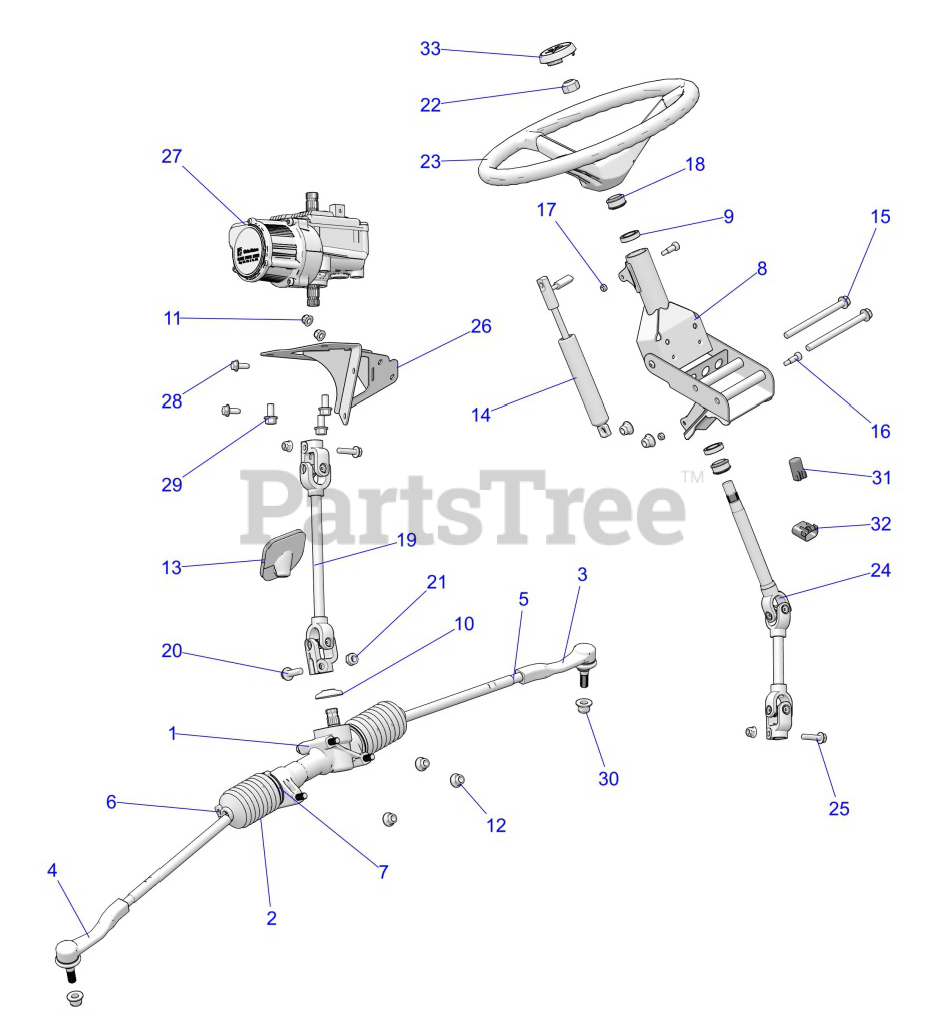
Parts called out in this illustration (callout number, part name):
1	ASM-GEAR BOX,STEERING
2	BOOT-DRIVER SIDE,RACK
3	D.S. OUTER TIE ROD
4	P.S. OUTER TIE ROD
5	NUT, JAM, LH THREAD
6	BELLOWS CLAMP, SMALL
8	ASM,TILT,STEERING,RVTD,M10.BLK
9	BEARING-STEERING
10	COVER-DUST,STEERING
11	NUT-M8X1.25,FLG,NYLOC-OLIVE D
12	NUT-M10X1.25,FLG,NYLOC-OLIVE D
13	GROMMET-STEERING
14	ASM-SHOCK,OIL LOCKING,MACH
15	BOLT-M10X1.25X130,HXFLG-OLIVED
16	BOLT-SHOULDER,M8-15,M6X1.0-BLK
17	NUT,NYLOK(10)
18	BUSHING-STEERING
19	SHAFT, STEERING, LOWER, W/JOINT, EPAS
20	SCR-HXFL-M10X1.5X40 10.9 ZPC
21	NUT-NY INS,M10X1.5,HEX,ZINC,YW
22	NUT-HEX-M16X2, 8 ZC NYL
23	WHEEL-STEERING,15"
24	SHAFT, STEERING, UPPER
25	SCR-HXFL-M8X1.25X40 10.9 ZFB
26	WELD-EPAS,MNT,BLK
28	BOLT-M8X1.25X20,HXFLG,TAP/R-OD
29	BOLT-M10X1.25X20,HXFLG-OLV D
30	NUT-M12X1.5,FLG,NYLOC-OLIVE D
